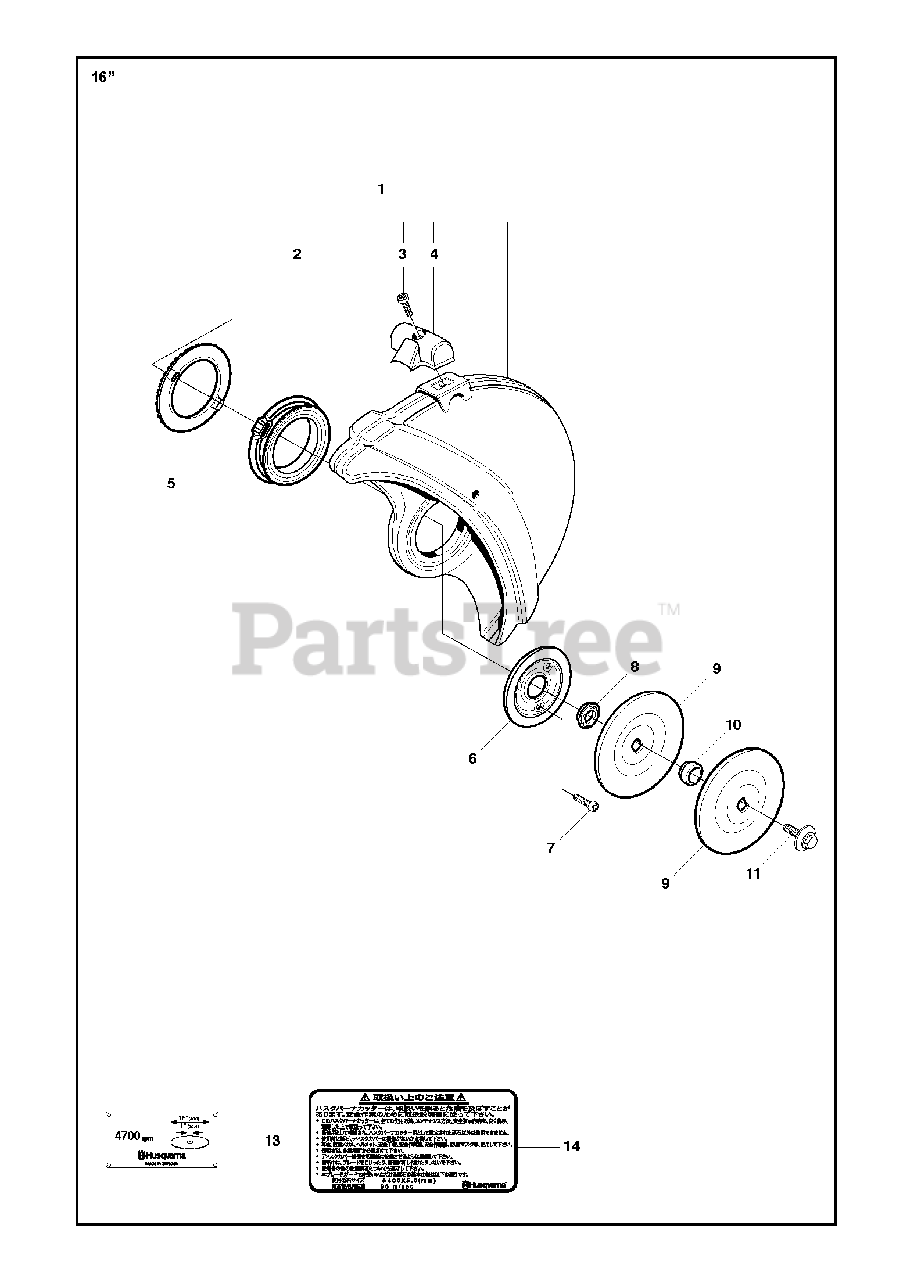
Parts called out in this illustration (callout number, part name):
1	BLADE GUARD"16"""
3	SCREW ITXSCM
7	SCREW ITXSCM
8	SUPPORT FLANGE
9	FLANGE WASHER
